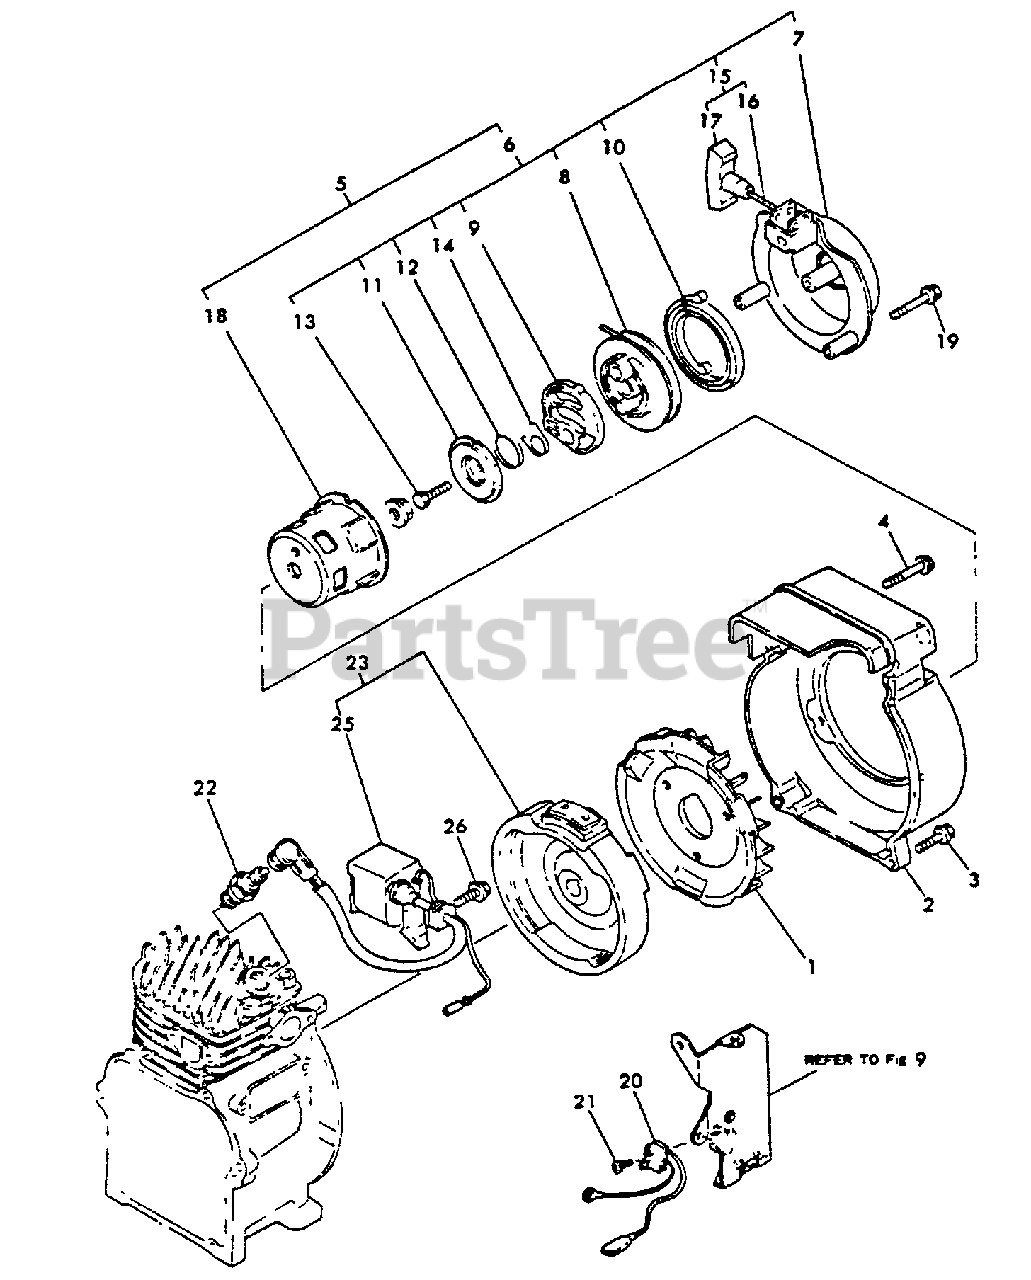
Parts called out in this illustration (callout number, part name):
1	FAN
2	COVER, FAN
3	BOLT - 6×30
4	BOLT - 6×30
5	STARTER ASSY
6	STARTER ASSY, RECOIL
7	STARTER CASE ASSY
8	PULLEY
9	RATCHET
10	SPRING
11	PLATE, FRICTION
12	SPRING, FRICTION
13	BOLT
14	SPRING, RETURN
15	STARTER ROPE ASSY
16	ROPE, STARTER
17	KNOB, STARTER
18	PULLEY, STARTER
19	BOLT - 6×35 -- PLATED
20	SWITCH, STOP
21	SCREW - 2×10 -- TAPPING
22	SPARK PLUG - BPM-8Y
23	FLYWHEEL MAGNETO ASSY
25	COIL, IGNITION
26	BOLT - 6×30
